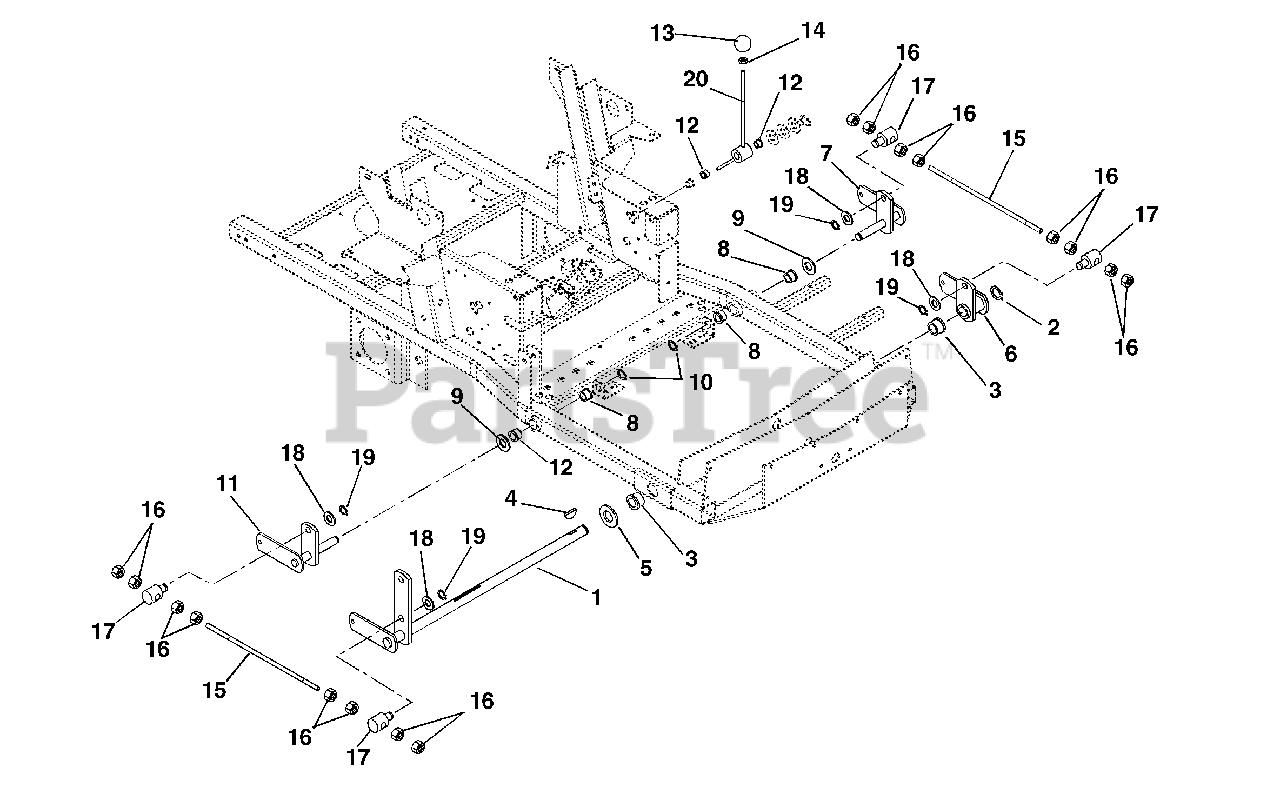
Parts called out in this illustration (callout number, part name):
1	Lift-Mower
2	Ring-Retaining-External 1.00 x .078
3	Bushing-Flange-Nylon 1.020 x 1.385 x .75 x 1.75
4	Key-Woodruff .25 x 1.00
5	Washer-Flat-Steel 1.063 x 2.00 x .134
6	Weldment, Lift Arm-Front
7	Weldment, Lift Arm-Shaft-Left Hand
8	Bushing-Flange-Nylon .762 x 1.0 x .580 x 1.48
9	Washer-Hardened-Steel .758 x 1.23 x .031
10	Ring-Retaining-External .689 x .077
11	Weldment, Lift Arm Shaft-Right Hand
12	Bushing-Flange .63 x 1.00 x .625
13	Knob-Steering Lock
14	Nut-Hex-Jam .375 -16
15	Rod-Lift Assist
16	Nut-Jam .50-13
17	Pivot-Mower Lift
18	Washer-Flat-Steel .630 x 1.005 x .062
19	Ring-Retaining-External .625 x 050
20	Lever-Deck Lift
